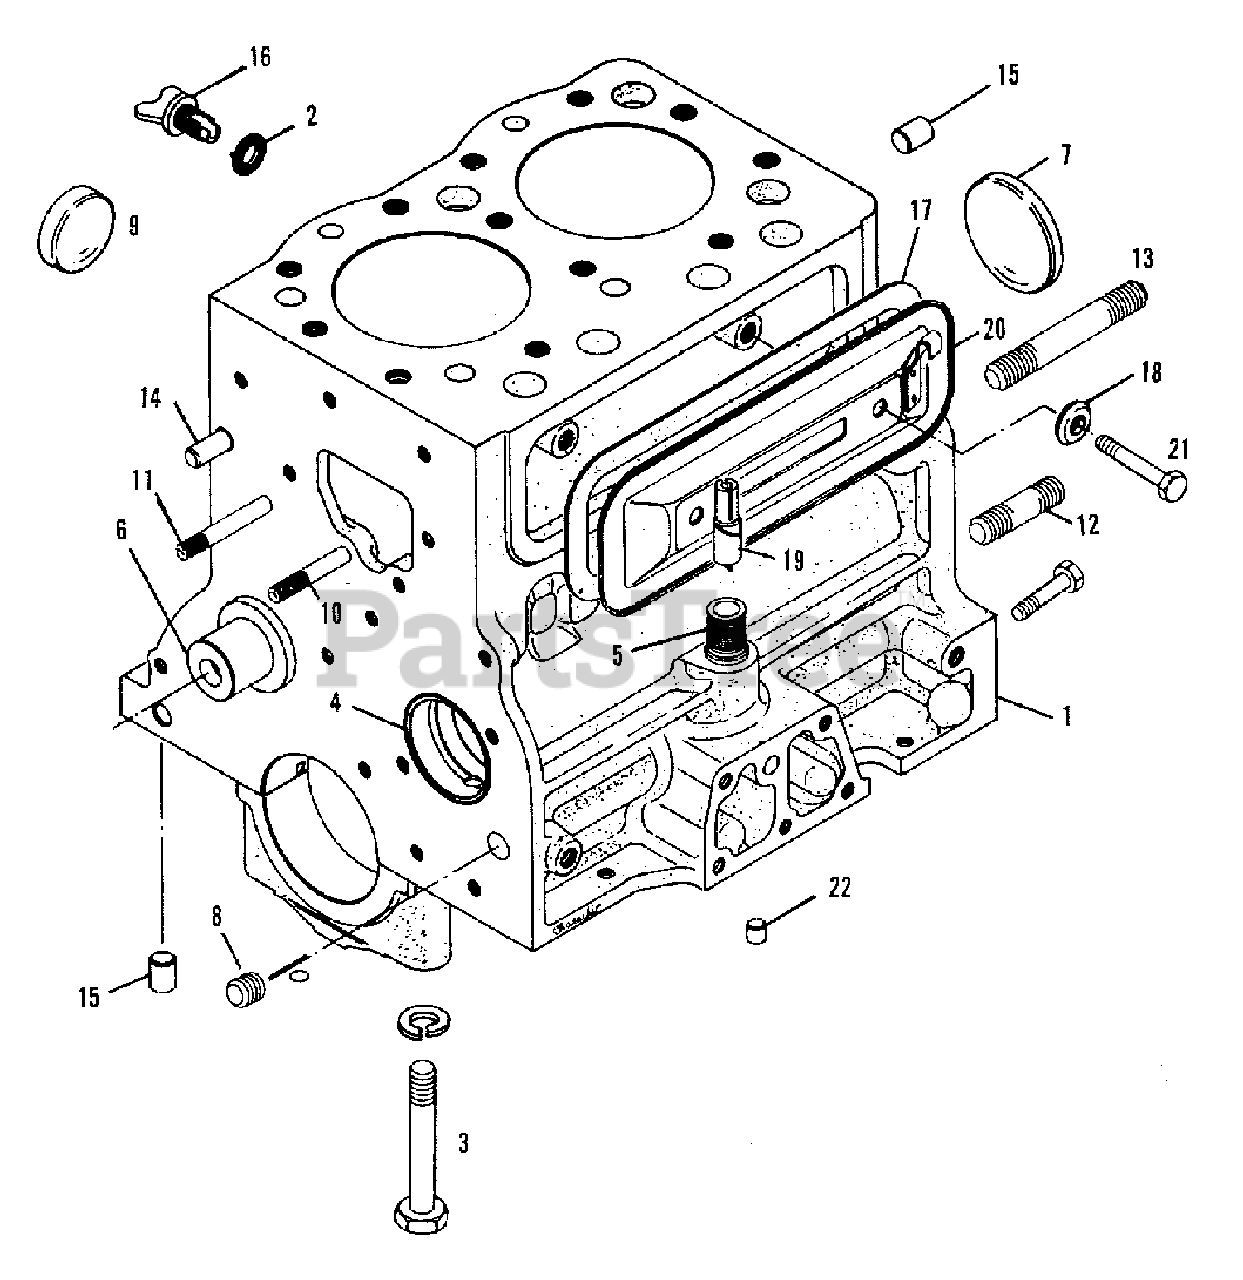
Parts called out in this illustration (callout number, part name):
1	BLOCK ASSEMBLY, cylinder (Incl. Item 3 thru 16)
2	GASKET, water drain plug
3	BOLT, M12 x 82 bearing cap
4	BEARING, cam shaft
5	CONNECTOR, hour meter cable
6	SHAFT, idle gear
10	STUD, M8 x 64 water pump
11	STUD, M8 x 66 gear cover
12	STUD, M12 x 38 rear plate
13	STUD, M12 x 113 clutch case
14	PIN dowel, front
15	PIN, dowel, rear
16	PLUG, water drain (Incl. Item 2)
19	ROD, cable drive
20	COVER, valve lifter chamber
21	CAPSCREW, block cover
22	PLUG M9 x 7
